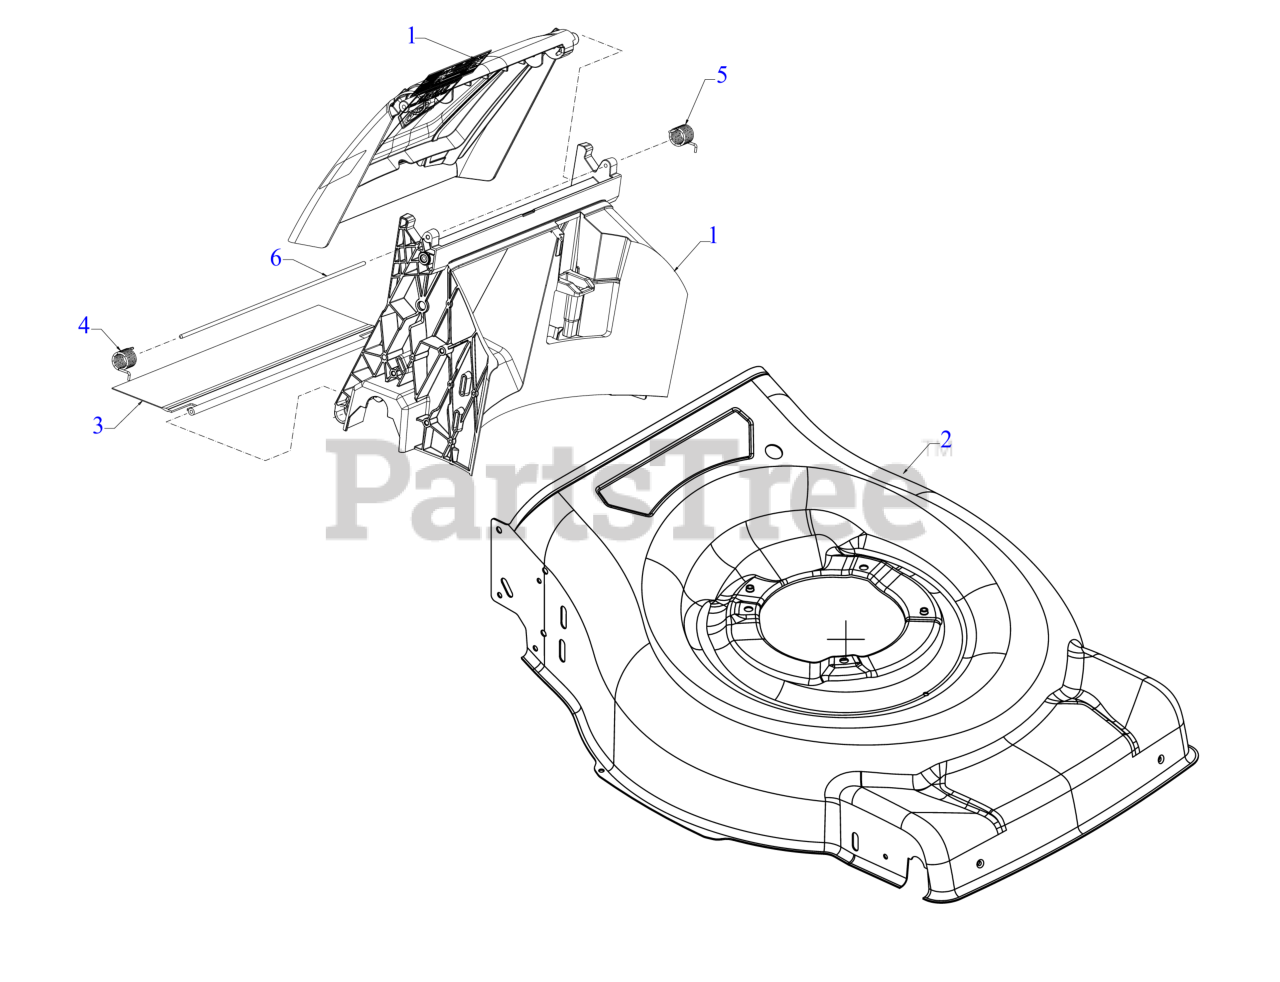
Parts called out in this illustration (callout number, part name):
1	BAFFLE ASSEMBLY
2	23" RWD DECK
3	TRAILSHIELD (4.54 x 18)
4	TORSION SPRING (RH)
5	TORSION SPRING (LH)
